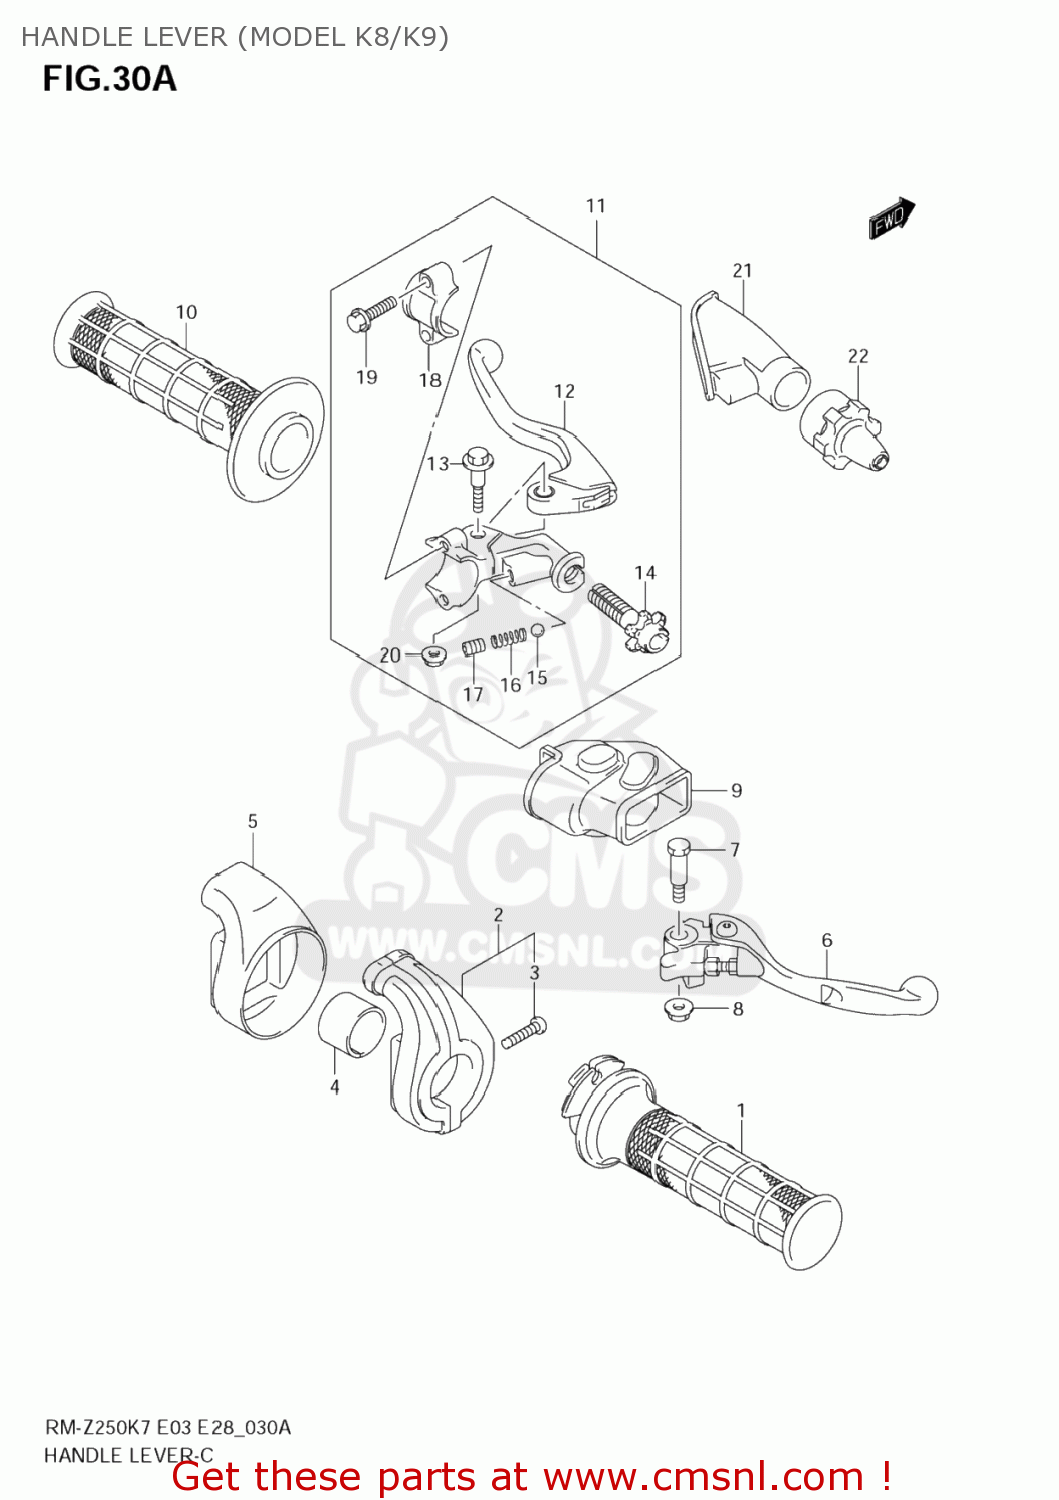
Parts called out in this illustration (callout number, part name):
1	GRIP,THROTTLE
2	CASE ASSY,THROTTLE
3	SCREW,CASE
4	COLLAR,THROTTLE CASE
5	COVER,THROTTLE CASE
6	LEVER ASSY,BRAKE
7	BOLT,BRAKE LEVER
8	NUT
9	COVER,BRAKE LEVER
10	GRIP,L
11	LEVER ASSY,CLUTCH
12	LEVER,CLUTCH
13	BOLT
14	ADJUSTER,CLUTCH CABLE
15	BALL
16	SPRING
17	SCREW(6X8)
18	BRACKET,CLUTCH LEVER HOLDER
19	BOLT,BRACKET
20	NUT
21	COVER,CLUTCH LEVER
22	COVER,CLUTCH ADJUSTER
